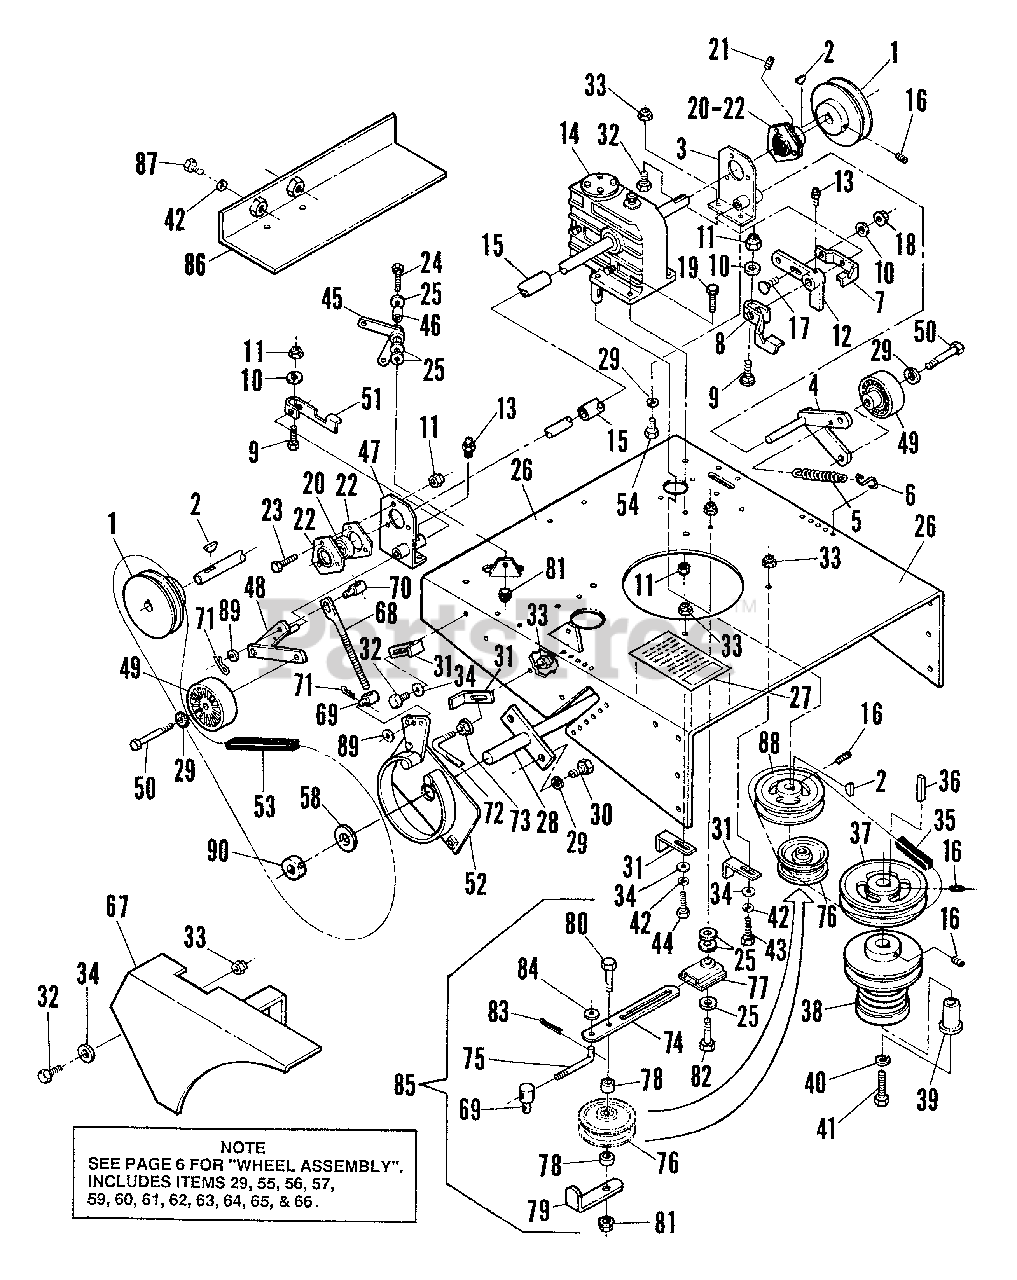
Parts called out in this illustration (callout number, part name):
1	PULLEY, Output w/Set Screw
2	KEY, Woodruff No. 605
3	BRACKET WELDMENT,Bearing Support
4	BELLCRANK, Traction Weldment
5	SPRING, Extension
6	HOOK, Spring(s)
7	TAB, Blade Switch
8	TAB, Traction Switch Left
9	BOLT, 1/4-20 x 1-1/4" Square Neck Carriage, Grade 2
10	WASHER, 1/4 SAE Flat
11	NUT, 1/4-20 Nyloc
12	BELLCRANK, Blade Control
13	FITTING, 1/4-20 Grease
14	BOX, Worm Gear Reduction
15	TUBE, Transmission Output Shaft
16	SCREW, 5/16-18 x 3/8" Set
17	BOLT, 1/4-20 x 3/4" Short Neck Carriage, Grade 5
18	NUT, 1/4-20 Hex Flange Lock
19	SCREW, 1/4-20 x 1" Hex Head Cap, Grade 5
20	BEARING, Flange w/Set Screws
21	SCREW, #10-32 x 1/4" Set Nyloc
22	PLATE, Flange
23	SCREW, 1/4-20 x 5/8" Hex Head Cap, Grade 5
24	SCREW, 3/8-16 x 1-3/4" Hex Head Cap, Grade 5
25	WASHER, 3/8 Std. Flat
26	REAR DECK w/Decal
27	DECAL, Caution
28	WELDMENT, Axle (36" & 48")
29	WASHER, 3/8" Split Lock
30	SCREW, 3/8-16 x 1" Hex Head Cap, Grade 5
31	BELT GUIDE new 23609
32	SCREW, 5/16-18 X 3/4" Hex Head Cap, Grade 2
33	NUT, 5/16-18 Hex Nyloc
34	WASHER, 5/16 Flat
35	BELT, Variable Speed (32" & 36")
36	KEY, 1/4" Square x 2-1/2"
37	PULLEY, w/Set Screws
38	PULLEY, Variable Speed w/Set Screws
39	SPACER, variable Speed
40	WASHER, 7/16 Split Lock
41	SCREW, 7/16-20 x 3" Hex Head Cap (Briggs)
42	WASHER, 5/16 Split Lock
43	SCREW, 5/16-18 x 1-3/4" Hex Head Cap, Grade 5 (Briggs)
44	SCREW, 5/16-18 x 2-1/4" Hex Head Cap, Grade 5(Briggs)
45	BELLCRANK
46	BUSHING, Powder Metal
47	BRACKET, Bearing Support
48	BELLCRANK, Traction Right
49	PULLEY, Idler
50	SCREW, 3/8-24 x 1-1/2" Hex Head Cap, Grade 2
51	TAB, Traction Switch
52	BRAKE ASSEMBLY, Right
53	BELT, Traction
54	SCREW, 3/8-16 x 3/4" Hex Head Cap, Grade 5
58	SPACER
67	FENDER, Right
68	LINKAGE, Brake
69	SWIVEL, Short
70	SWIVEL, Long
71	HAIRPIN, #2 Cotter
72	SCRAPER
73	NUT, 5/16-18 Hex Flange Lock, Grade 5
74	BAR, Slide
75	LINKAGE, Variable Speed Adjustment
76	PULLEY, Idler w/Bushing
77	BRACKET, Slide
78	SPACER (1" O.D. x 13/32 I.D. x 3/8")
79	GUIDE, Belt
80	SCREW, 3/8-16 x 2-1/2" Hex Head Cap, Grade 2
81	NUT, 3/8-16 Hex Flange Lock
82	SCREW, 3/8-16 x 1-1/2" Hex Head Cap, Grade 5
83	PIN, 3/32 x 1/2" Cotter
84	WASHER, 5/16 SAE Flat
85	SLIDE, Variable Speed Assembly
86	SHIELD, Lower Belt
87	SCREW, 5/16-18 x1" Hex Head Cap, Grade 2
88	PULLEY, Transmission w/Set Screws (32" & 36")
89	WASHER, Brake Linkage
90	COLLAR, 7/8" Clamp w/Set Screw
